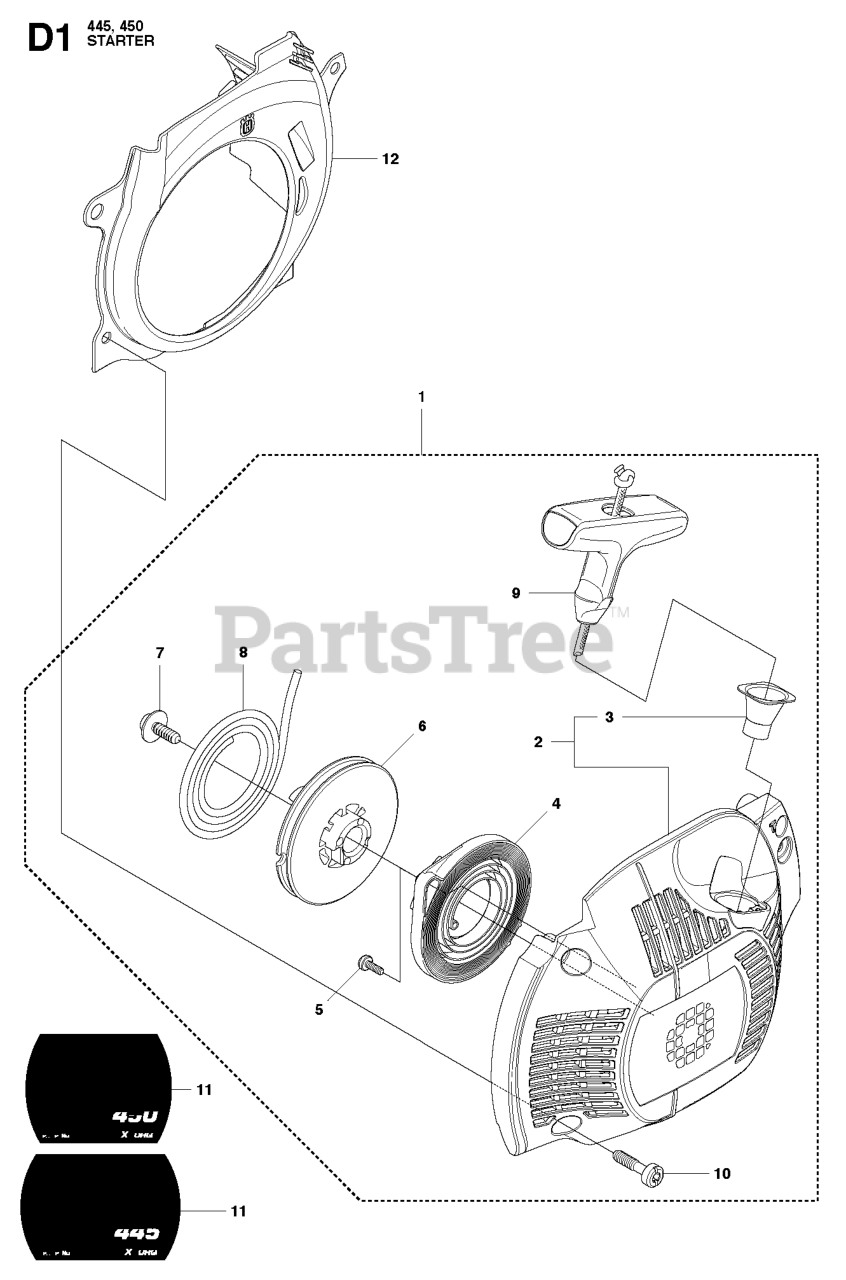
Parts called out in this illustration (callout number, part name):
1	STARTER ASSY
2	STARTER HOUSING
4	SPRING CASSETTE ASSY
6	PULLEY
8	STARTER ROPE
11	LABEL
12	COOLING AIR CONDUCTOR
